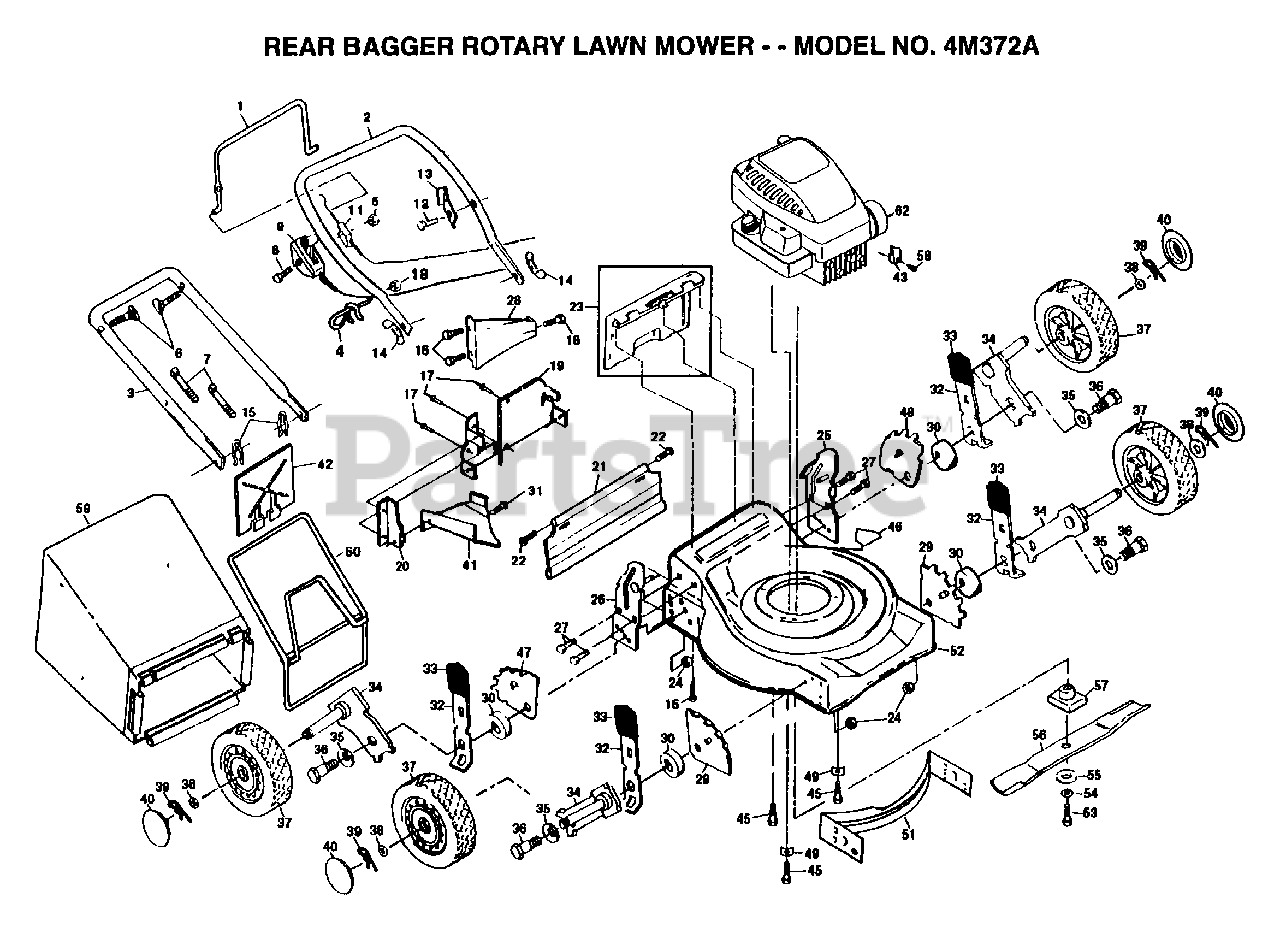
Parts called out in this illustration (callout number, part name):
1	CONTROL BAR
4	ROPE GUIDE
6	BOLT.HANDLE.LM
8	SCREW.HXHD.WASH.
9	"CONTROL, THROTTLE"
10	GUIDE CLIP PM
11	"CABLE,ENG ZONE CO"
12	TAPPING SCREW
13	"BRKT,UPSTOP"
14	"NUT,WING PM"
15	HAIRPIN COTTER
16	SCREW
17	BLIND RIVET
18	NUT
19	PLATE.BACK
21	SKIRT.REAR.FGD.22
22	HINGE SCREW
24	LOCKNUT PM
27	SCREW
28	REAR BAFFLE
29	BRACKET.ADJ.9POS.
31	SCREW PM
32	SPRING SELECTOR
33	KNOB PM
34	AXLE ARM
35	"WASHER, BELLEVIL."
36	BOLT SHLD 3/8-16
38	WASHER
39	RETAINER CLIP PM
40	HUB CAP
41	DISCHARGE BAFFLE
42	MULCHER PLATE
43	CABLE CLAMP
45	SCREW
46	DECAL HYT
47	BRACKET.ADJ.9.RH
48	BRACKET.ADJ.9.LH
52	KIT.HSG.22RD.PUSH
53	SCREW
54	LOCKWASHER
55	"WASHER,HARDEN"
56	"BLADE.MULCH.22"""
57	ADAPTOR.BLADE.LM
58	SCREW PM
59	GRASS BAG
60	CATCHER FRAME
